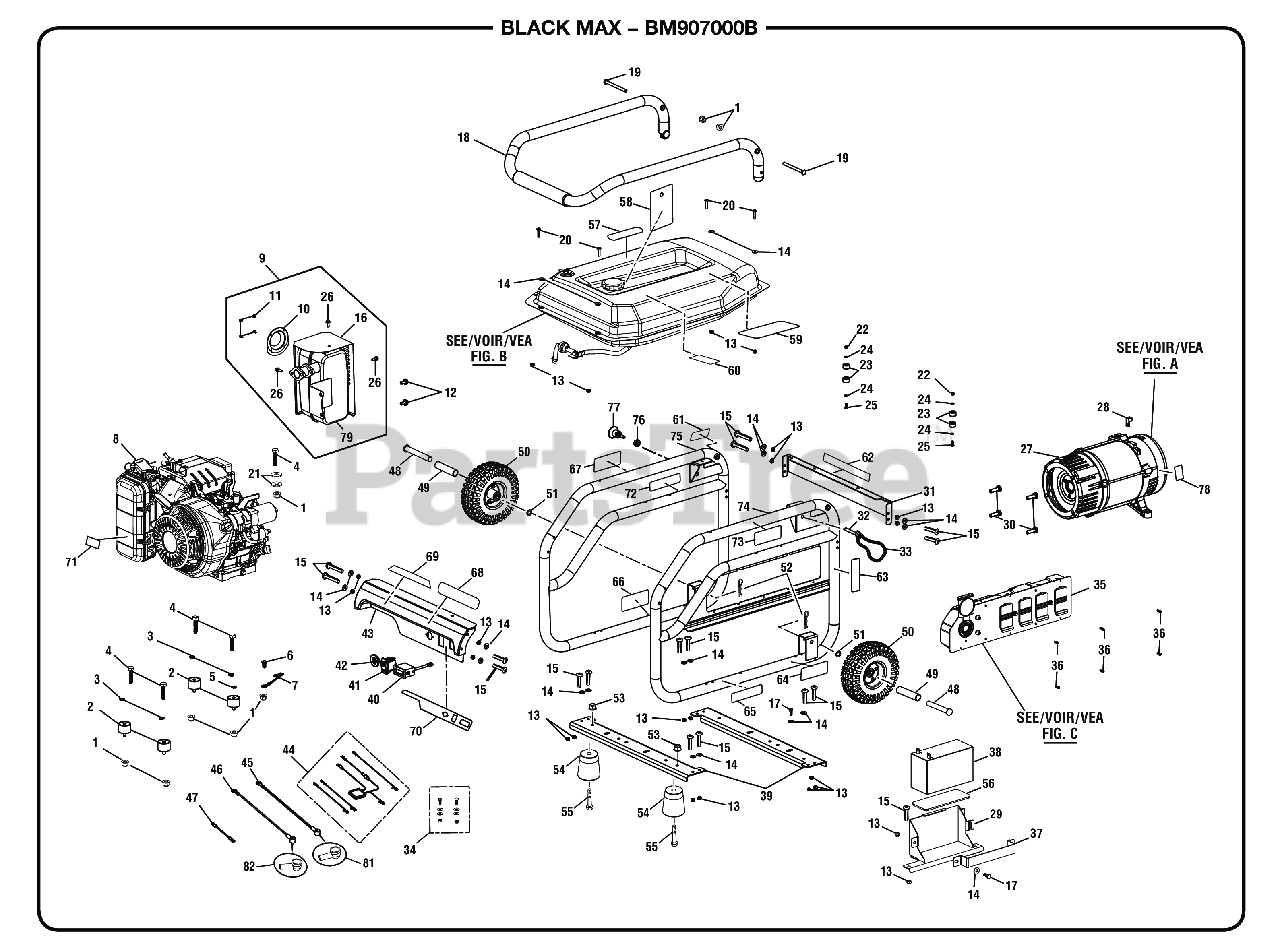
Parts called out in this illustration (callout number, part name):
1	Lock Nut (M8)
3	Washer (M8)
4	Bolt (M8 x 35 mm, Hex Hd.)
5	Star Washer (M8)
6	Bolt (M8 x 15 mm)
7	Ground Wire Assembly
8	Engine
9	Muffler Assembly
10	Spark Arrestor
11	Screw (8-32 x 3/8 in.)
12	Bolt (5/16-24 x 0.6 in.)
13	Lock Nut (M6)
14	Washer (M6)
15	Screw (M6 x 50 mm, Torx Hd.)
16	Heat Shield
17	Bolt (M6 x 16 mm)
18	Handle Assembly
19	Bolt (M8 x 98 mm, Flat Hd.)
20	Bolt (M6 x 25 mm, Torx Pan Hd)
21	Washer (5/16 in.)
23	Rubber Bumper
24	Washer (M4)
25	Screw (M4 x 12 mm)
26	Bolt (M6 x 9 mm)
27	Generator Head w/AVR
28	Ground Lug
29	Battery Tray
30	Bolt (3/8-16 x 1 in.)
31	Fuel Tank Support (Back)
32	Handle Lock Pin
34	Fastener Kit (Wiring)
35	Control Panel Assembly
36	Screw (6-20 x 3/8 in., Pan Hd.)
37	Battery Bracket
38	Battery
39	Frame Crossbar
40	Hour Meter
41	Engine Switch
42	Fuel Valve Bezel
43	Fuel Tank Support (Front)
44	Wiring Harness
45	Battery Cable (Black)
46	Battery Cable (Red)
47	Bonding Wire
51	Washer (M10)
52	Hitch Pin
53	Lock Nut (M8 x 1.25)
54	Rubber Foot
55	Bolt (M8 x 45 mm, Hex Hd.)
57	CPSC Label
58	Warning Hangtag
59	Danger Label
60	E85 Label
61	Handle Release Label
62	Ground Warning Label
63	Lock Pin Label
64	Inquiries Label
65	Lubricant Label
66	Combustion Label
67	Fire Distance Label
68	Logo Label
69	Honda Label
70	Start Label
71	Electric Start Label
72	Hot Surface Label
73	Fire Danger Label
74	Frame (Right)
75	Frame (Left)
76	Hex Jam Nut (1/2-20)
77	Handle Release Pin
78	Ground Label
80	Rubber Sheet
